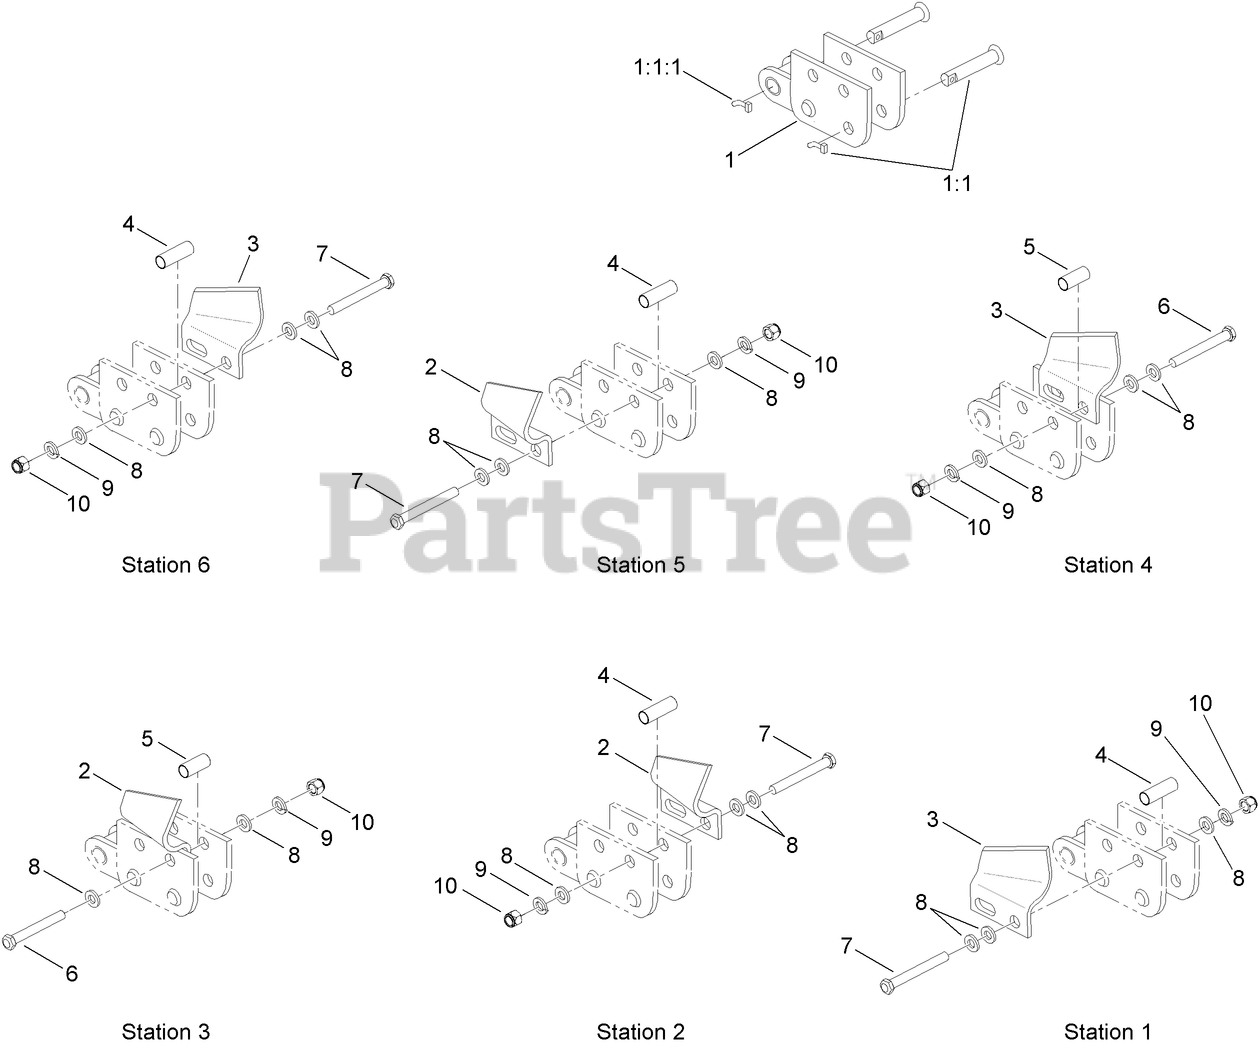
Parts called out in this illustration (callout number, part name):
1	CHAIN REPAIR LINK ASM
1:1	NOTCHED PIN AND KEEPER ASM
1:1:1	PIN-KEEPER
2	CUTTER-CUP, RH
3	CUTTER-CUP, LH
4	SPACER-TUBE, OUTSIDE MOUNT
5	SPACER-TUBE, INSIDE CUP MOUNT
6	BOLT-HH
7	BOLT-HH
8	WASHER-FLAT
9	WASHER-LOCK
10	NUT-LOCK
